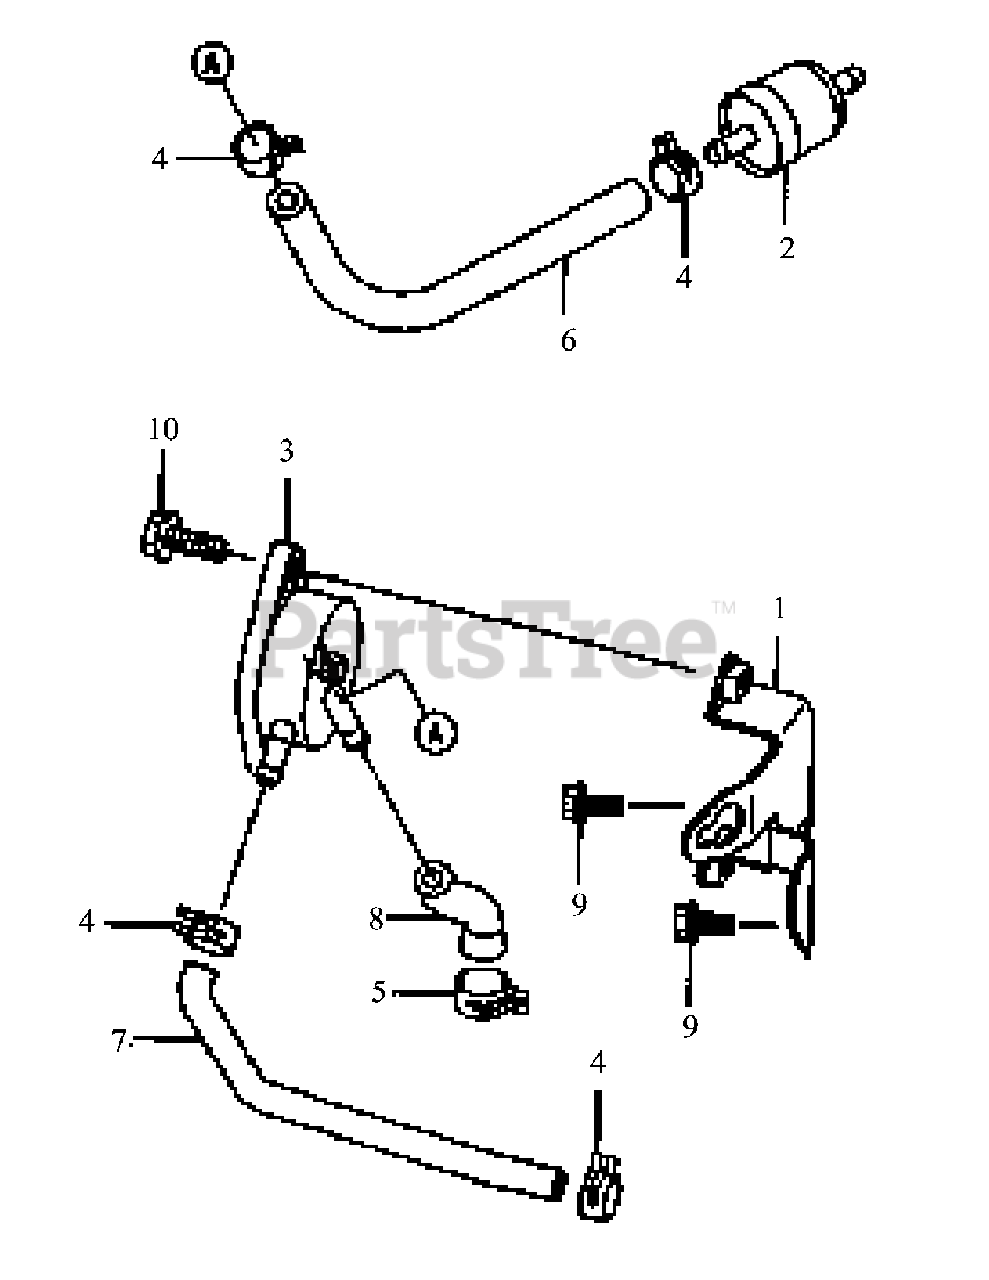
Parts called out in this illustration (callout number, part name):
2	Filter-Fuel
3	Pump-Fuel
4	Clamp
6	Tube 6.35x12.7x160
